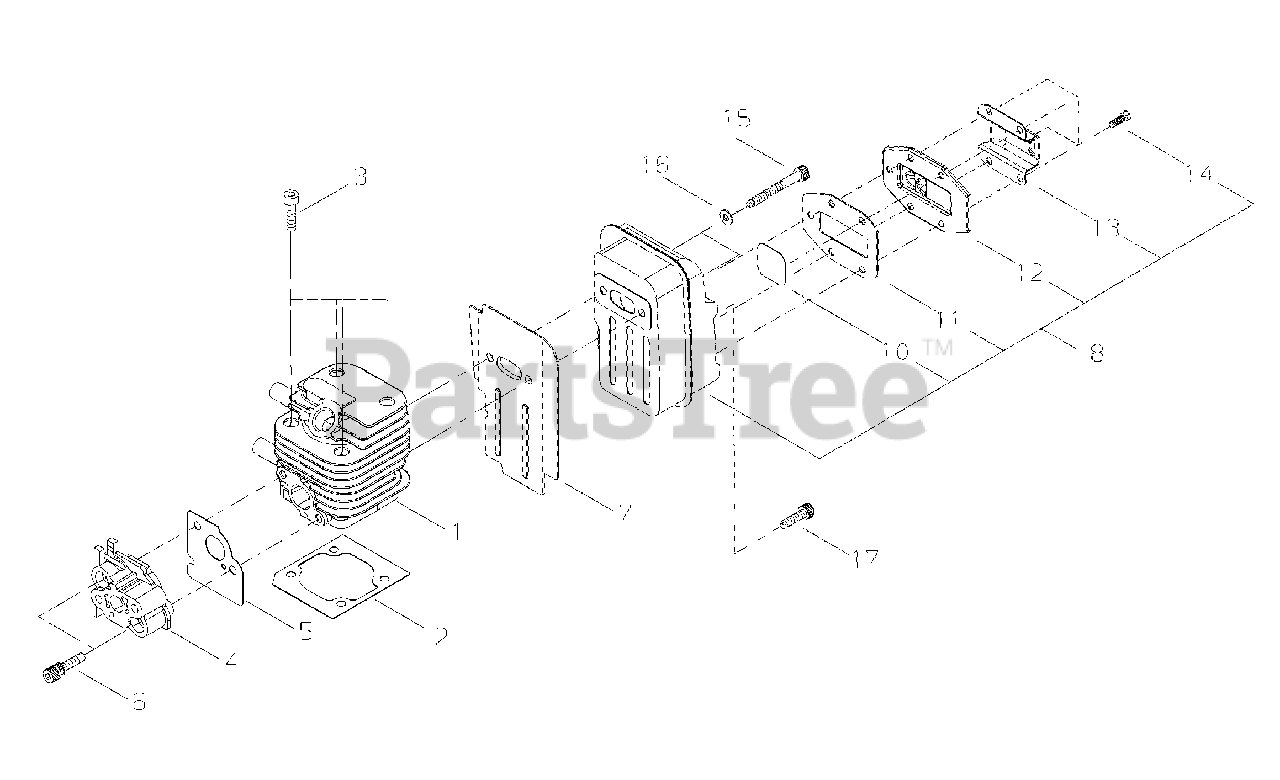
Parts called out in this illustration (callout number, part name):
1	CYLINDER
2	GASKET, CYLINDER
3	SCREW - 5X16
4	INSULATOR
5	GASKET, INTAKE
6	SCREW - 5X30
7	SHIELD, EXHAUST
8	MUFFLER ASSY
10	SCREEN, SPARK ARRESTOR
11	GASKET, EXHAUST
12	GUIDE, EXHAUST - INNER
13	GUIDE, EXHAUST - OUTER
14	SCREW - 4X8
15	SCREW - 5X55
16	WASHER - 5
17	SCREW - 5X12
